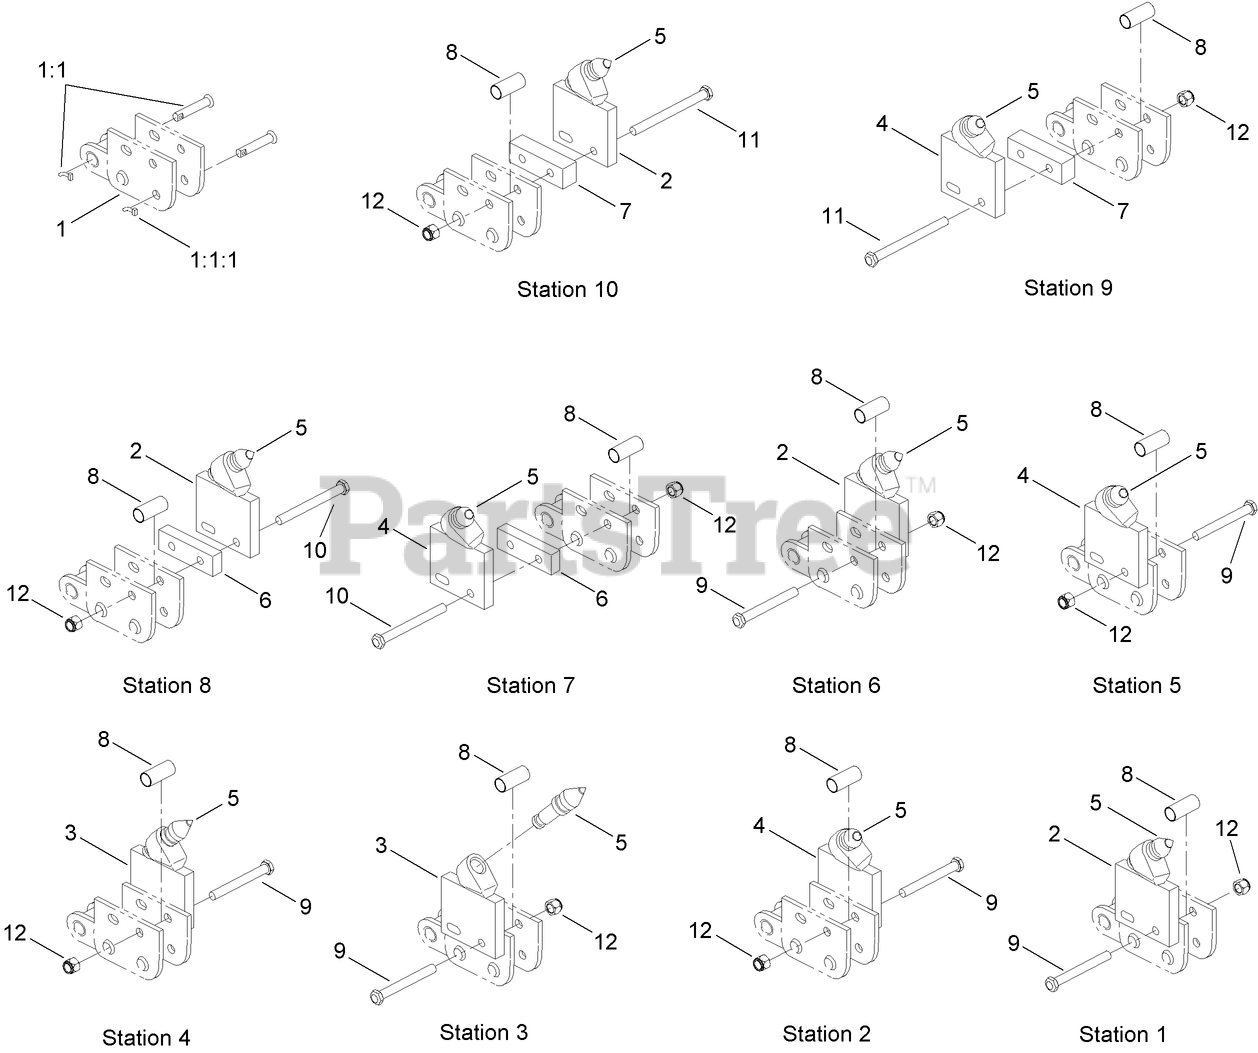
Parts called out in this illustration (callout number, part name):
1	CHAIN REPAIR LINK ASM
1:1	NOTCHED PIN AND KEEPER ASM
1:1:1	PIN-KEEPER
2	HOLDER-BIT, LH
3	HOLDER-BIT, STRAIGHT
4	HOLDER-BIT, RH
5	BIT AND CLIP, CARBIDE
6	SPACER-FLAT (.500 Inch)
7	SPACER-FLAT (1.00 INCH)
8	SPACER-TUBE, OUTSIDE MOUNT
9	BOLT-HH
10	BOLT-HH
11	BOLT-HH
12	NUT-LOCK
